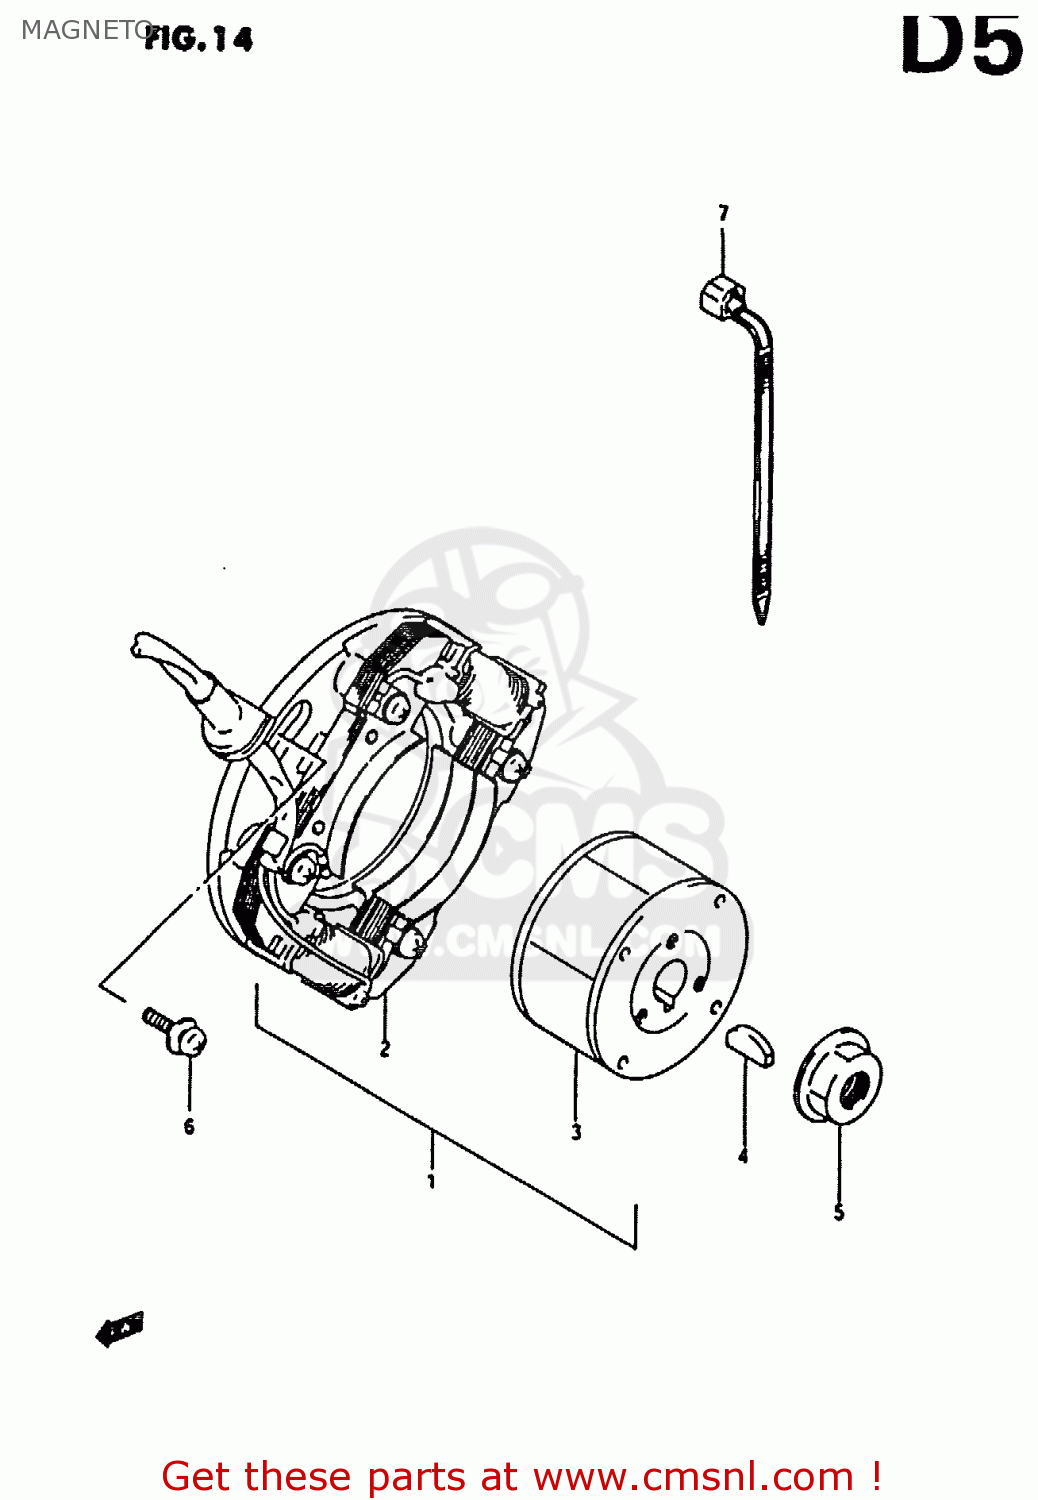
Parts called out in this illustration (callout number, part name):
1	MAGNETO ASSEMBLY
2	STATOR
3	ROTOR
4	KEY
5	NUT
6	SCREW
7	CLAMP L:165
